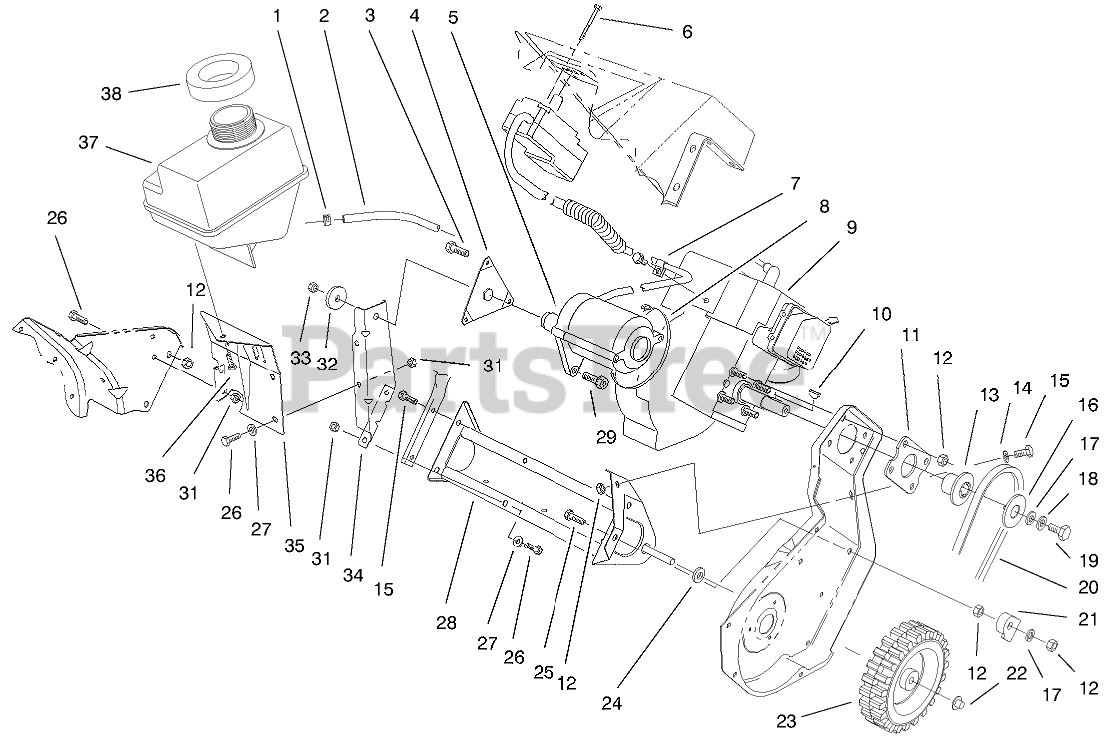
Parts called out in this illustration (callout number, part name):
1	CLAMP-HOSE
2	LINE-FUEL
3	WASHER-LOCK / EXT
3	SCREW
4	BRACKET AND STUD ASM
5	ASM-Switch Housing
6	SCREW-PLASTITE
7	CLAMP
8	TIE-CABLE
9	ASM-Engine
10	KEY-WOODRUFF
11	PLATE-ENGINE
12	NUT-LOCK, NI
13	Hub-HALF SHEAVE
14	WASHER-PLAIN
15	SCREW-HH
16	CAP-HALF SHEAVE
17	WASHER-FLAT
18	WASHER-BELLEVILLE
19	SCREW-HH
20	V-BELT
21	GUIDE-CABLE
22	RETAINER-PUSH ON
23	WHEEL
24	SPACER-PLASTIC
25	SCREW-HH
26	SCREW-HH
27	WASHER-FLAT
29	SCREW-HH, TORX
31	NUT-LOCK, NI
32	WASHER-SUPPORT, ENGINE
33	NUT-LOCK, NI
34	SUPPORT-ENGINE
35	BRACKET-TANK
36	SCREW-SHWH, THREAD FORMING
37	Tank-Gas
38	SEAL-FOAM
